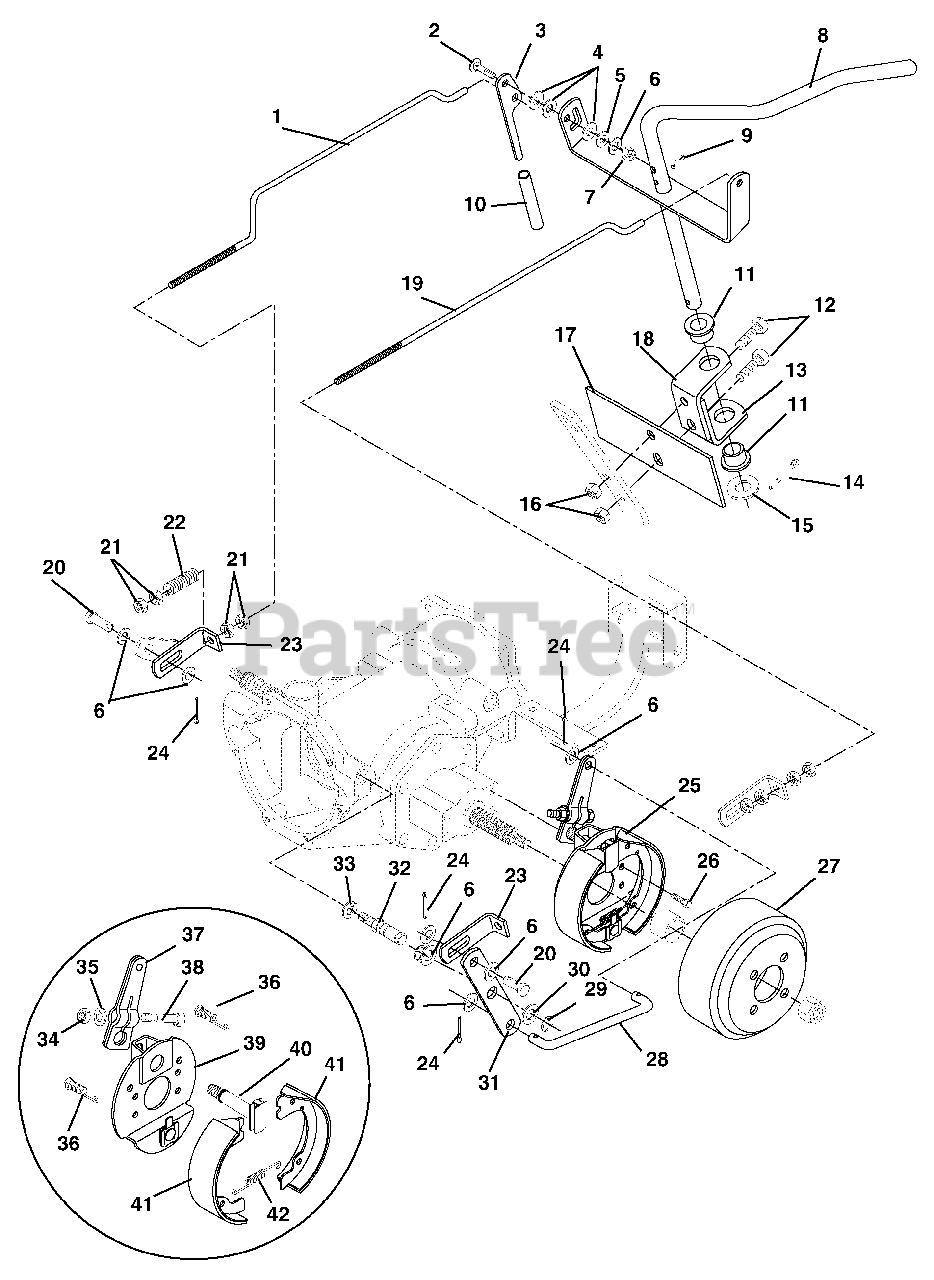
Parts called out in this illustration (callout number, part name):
1	Rod-Brake Right Hand
2	Bolt-Round Head Square Neck .38-16 x 1.50
3	Handle-Parking Brake
4	Washer-Flat-Nylon .375 x .75 x .060
5	Washer-Rubber .375 x .75 x .125
6	Washer-Flat-Steel .406 x .812 x .065
7	Nut-Locking-Center .38-16 Grade 2
8	Weldment-Brake Handle
9	Pin-Roll .313 x 2.00
10	Grip-Brake Handle
11	Bushing-Flange 1.082 x 1.385 x .870 x 1.750
12	Bolt-Hex .50-13 x 2.00 Grade 5
13	Bracket-Brake Handle
14	Pin-Cotter .188 x 1.50
15	Washer-Flat-Steel 1.120 x 1.500 x .092
16	Nut-Locking-Center .50-13 Grade 5
17	Plate-Instruction
18	Bracket-Brake Handle
19	Rod-Brake Left Hand
20	Pin-Clevis 3/8 x .750
21	Nut-Jam .375-16
22	Spring-Compression .105 x .61 x 2.50
23	Bracket-Adjustment
24	Pin-Cotter .09 x .75
25	Brake 7 x 1-3/4 Mechanical
26	Bolt-Hex .380-16 x .75
27	Drum, Brake
28	Rod-Brake Link
29	Ring-Retaining-External .625 x .042
30	Washer-Flat-Steel .656 x 1.312 x .095
31	Plate-Pivot
32	Stud-Pivot
33	Washer-Lock .125 Reg.
34	Nut-Jam .312-24 Grade 2
35	Washer-Lock .313 x .078
36	Spring-Shoe Ret Box
37	Arm-Cam Lever
38	Bolt-Hex .31-24 x 1.75
39	Plate-Back
40	Cam-Brake
41	Kit-Brake Shoe
42	Spring-Shoe Return
